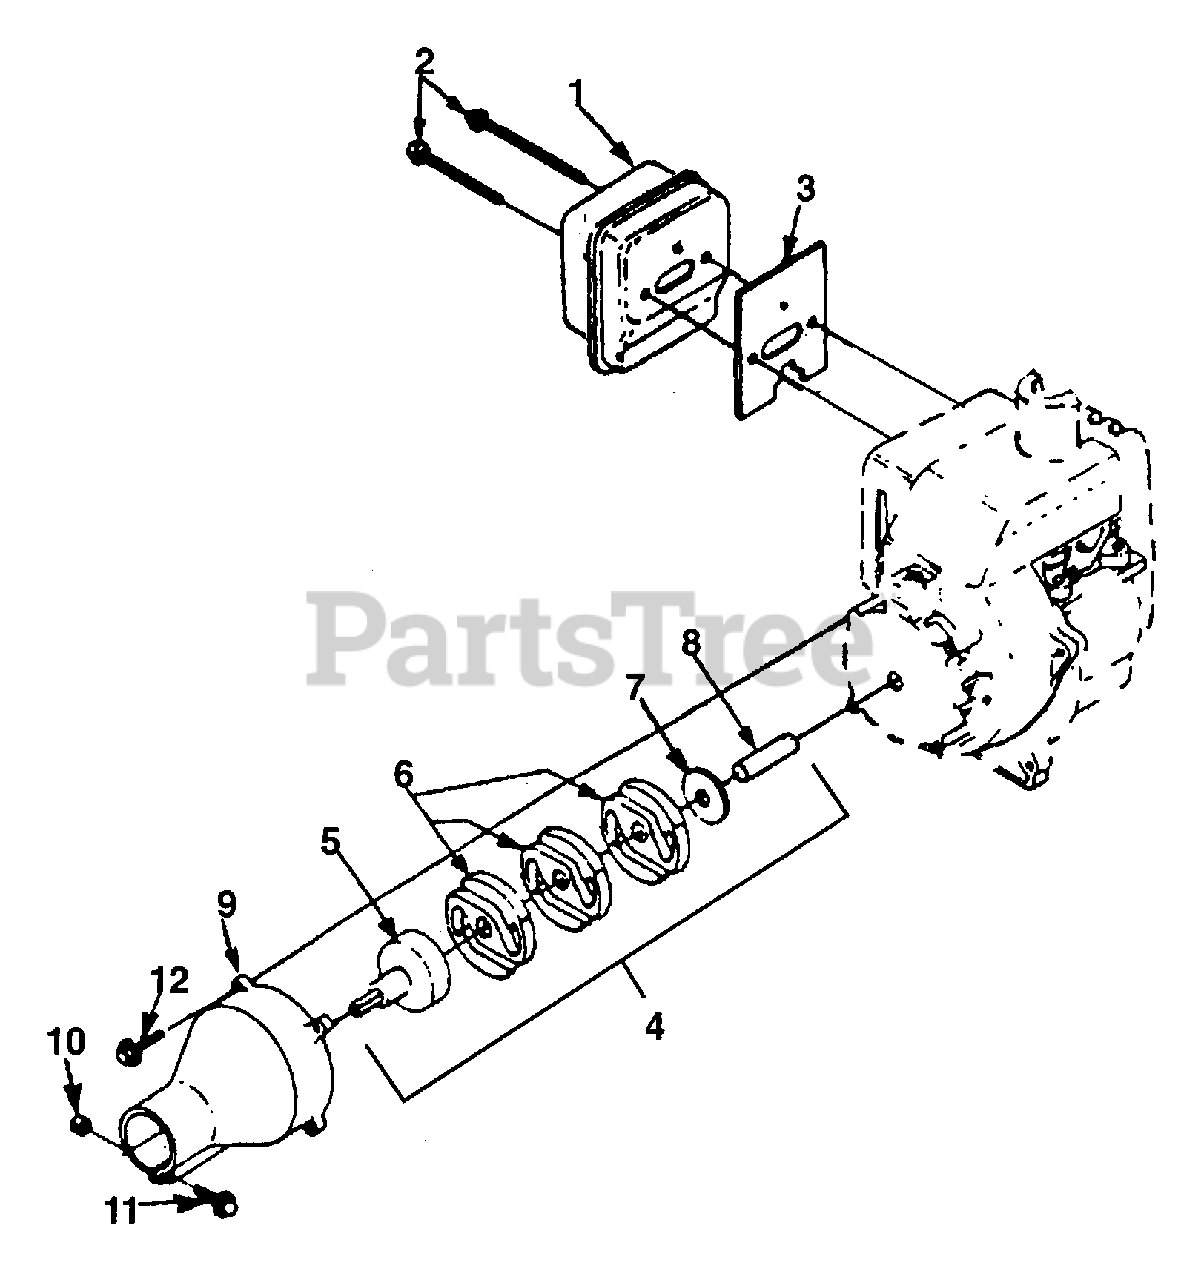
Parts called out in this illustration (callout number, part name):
1	Complete Muffler
2	Screw-Sems Hex Hd.
3	Muffler Gasket
4	Clutch & Drum Kit
5	Drum & Connector
6	Clutch
7	Washer, Clutch
9	Tube Adapter Kit
10	Nut, Lock
11	Screw (10-24 X 1 1/8")
12	Screw (10-24 X 7/8")
